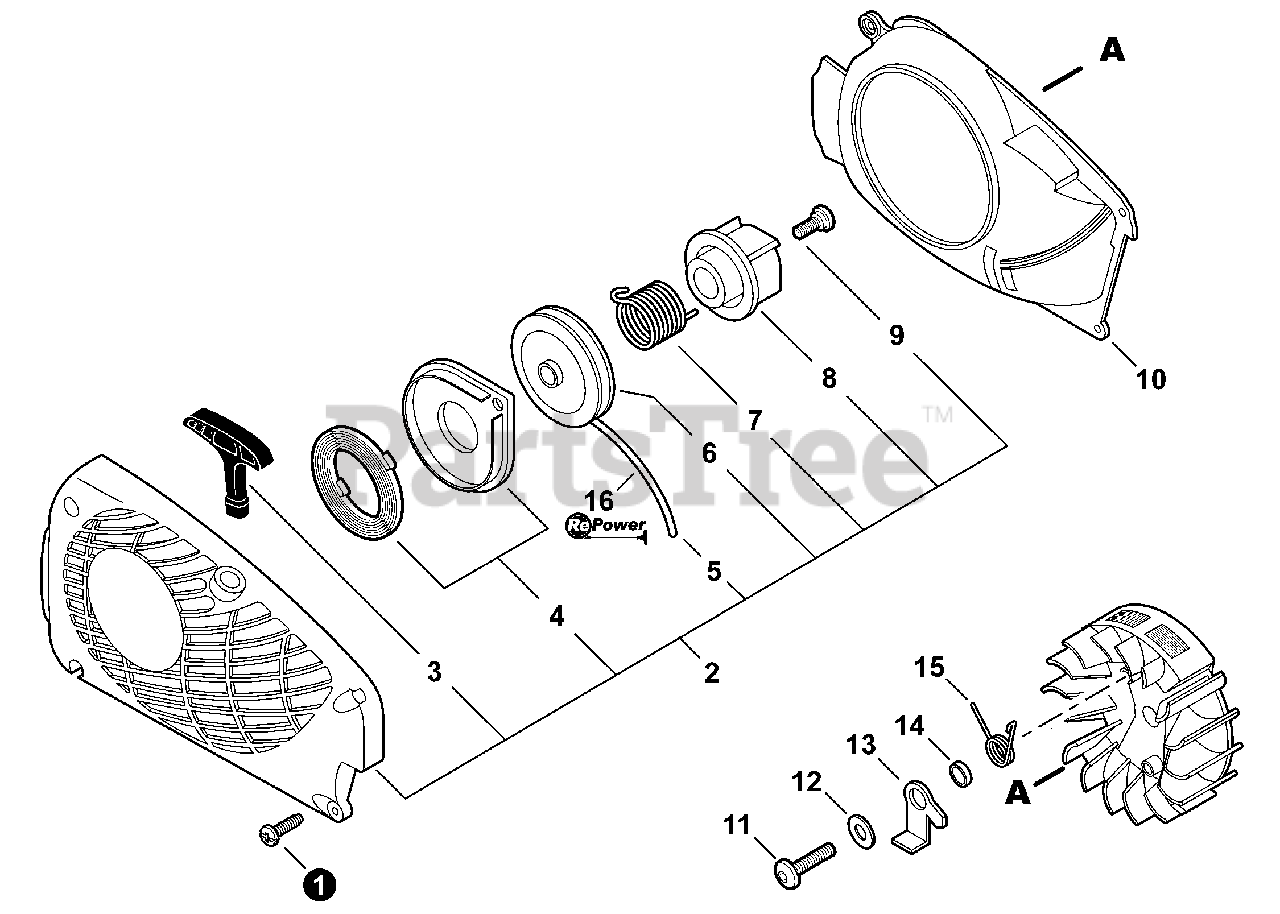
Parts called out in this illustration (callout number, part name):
1	SCREW 4×16
2	STARTER ASSY, RECOIL
3	GRIP, STARTER
4	SPRING KIT, RECOIL
5	ROPE, STARTER 3.5×900
6	REEL, ROPE
7	SPRING, TORSION
8	PAWL CATCHER
9	SCREW
10	COVER, FAN
11	BOLT 5×14
12	WASHER 5.5×12×0.8
14	SPACER 5.2×8×2.1
15	SPRING, TORSION
16	BULK STARTER ROPE - Ø 3.5 MM×61 M
